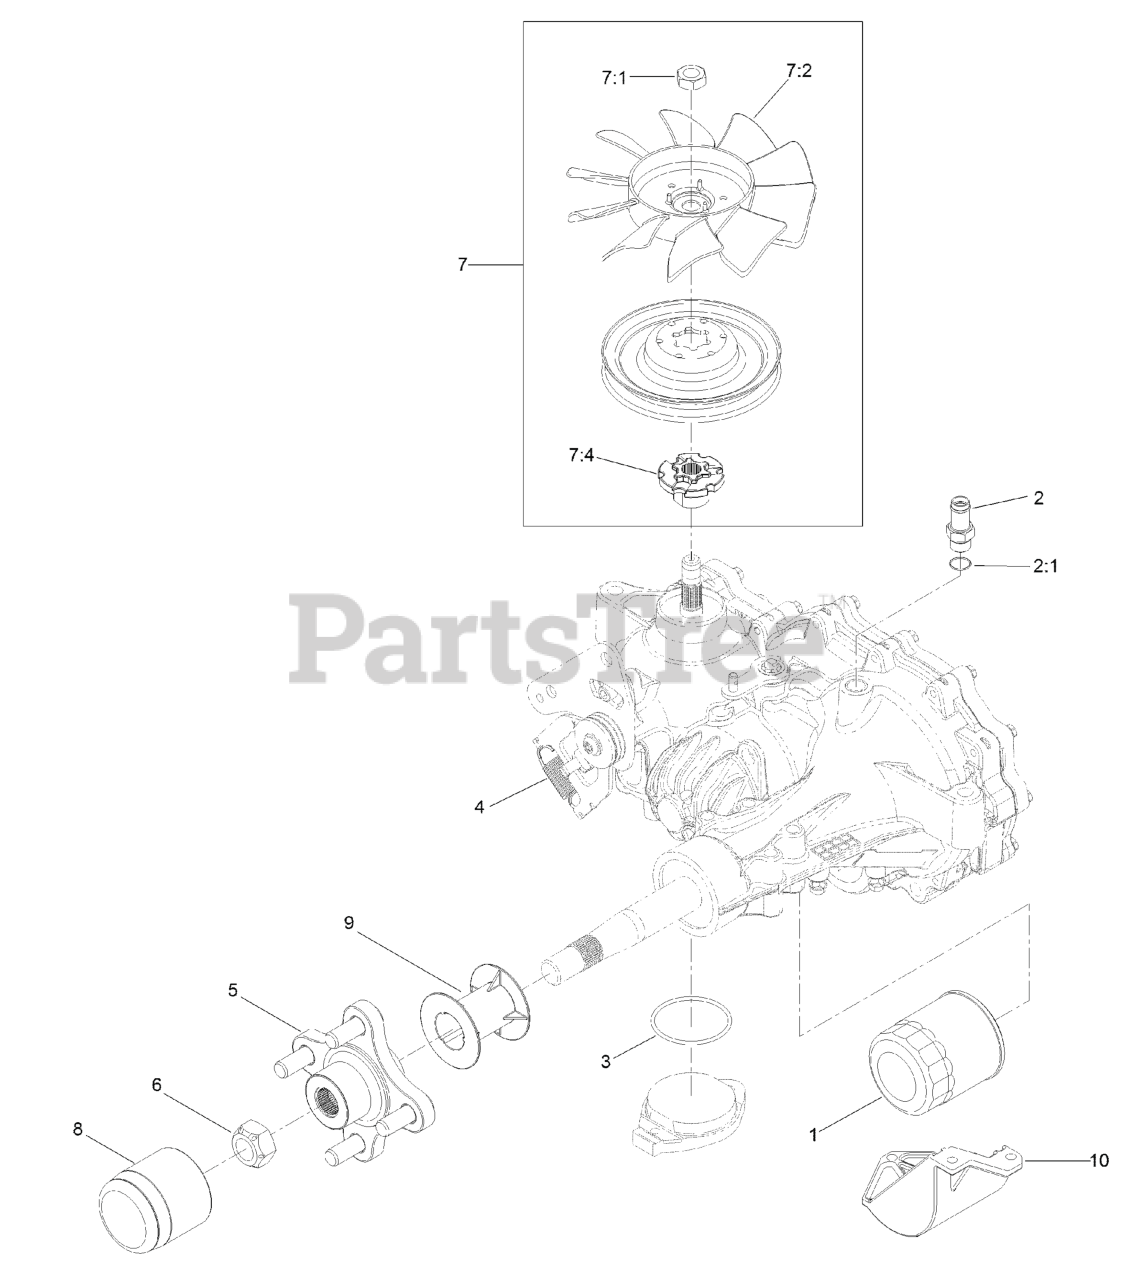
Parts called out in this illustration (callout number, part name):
1	ELEMENT-OIL FILTER, HYD
2	ADAPTER-STRAIGHT
2:1	O-RING
3	O RING-SEAL
4	SPRING-EXTENSION
5	HUB-OFFSET
6	NUT-HUB
7	FAN AND PULLEY KIT
7:4	HUB-PULLEY
8	CAP-AXLE, LONG
9	TUBE-AXLE
10	GUARD-FILTER, LH
99	BRAKE SHAFT SEAL KIT
